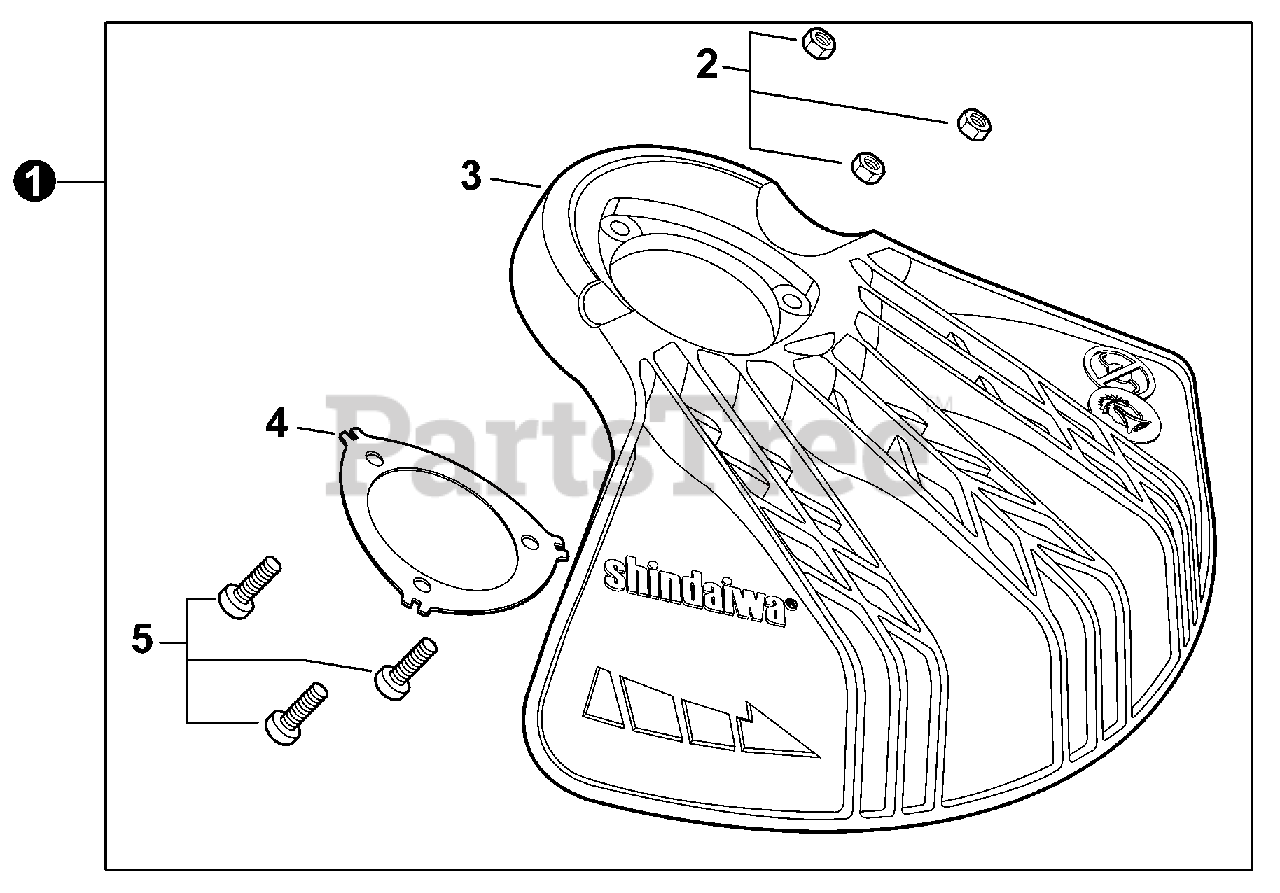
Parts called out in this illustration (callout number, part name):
1	DEBRIS SHIELD KIT - BLADE
2	NUT, LOCK M5
3	SHIELD, DEBRIS - BLADE
4	PLATE, SHIELD
5	BOLT, TORX 5×25
